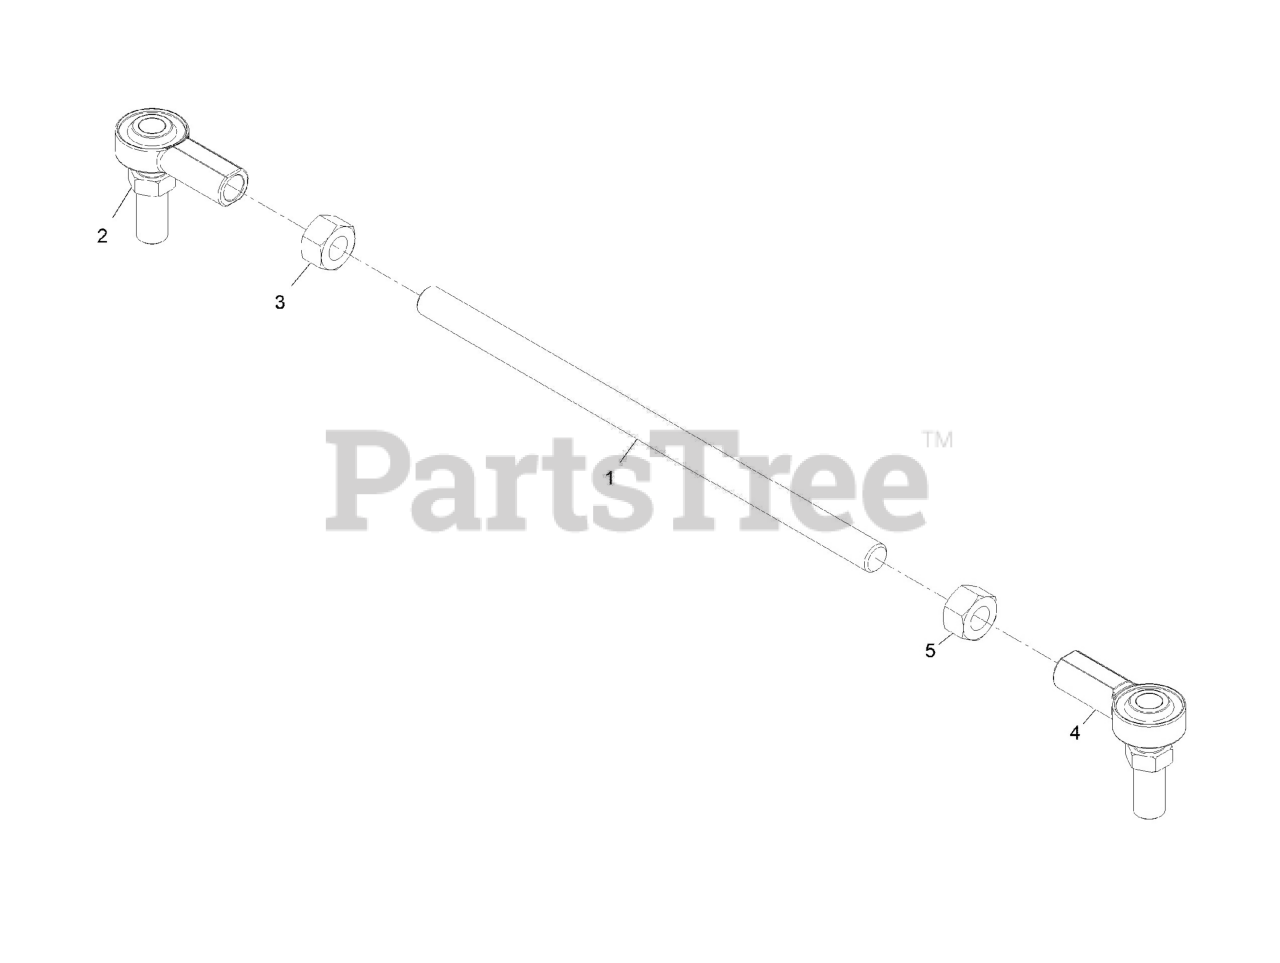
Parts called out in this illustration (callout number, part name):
2	ROD-END, RH
3	NUT-HEX
4	ROD-END, LH
5	NUT-HEX, LH
